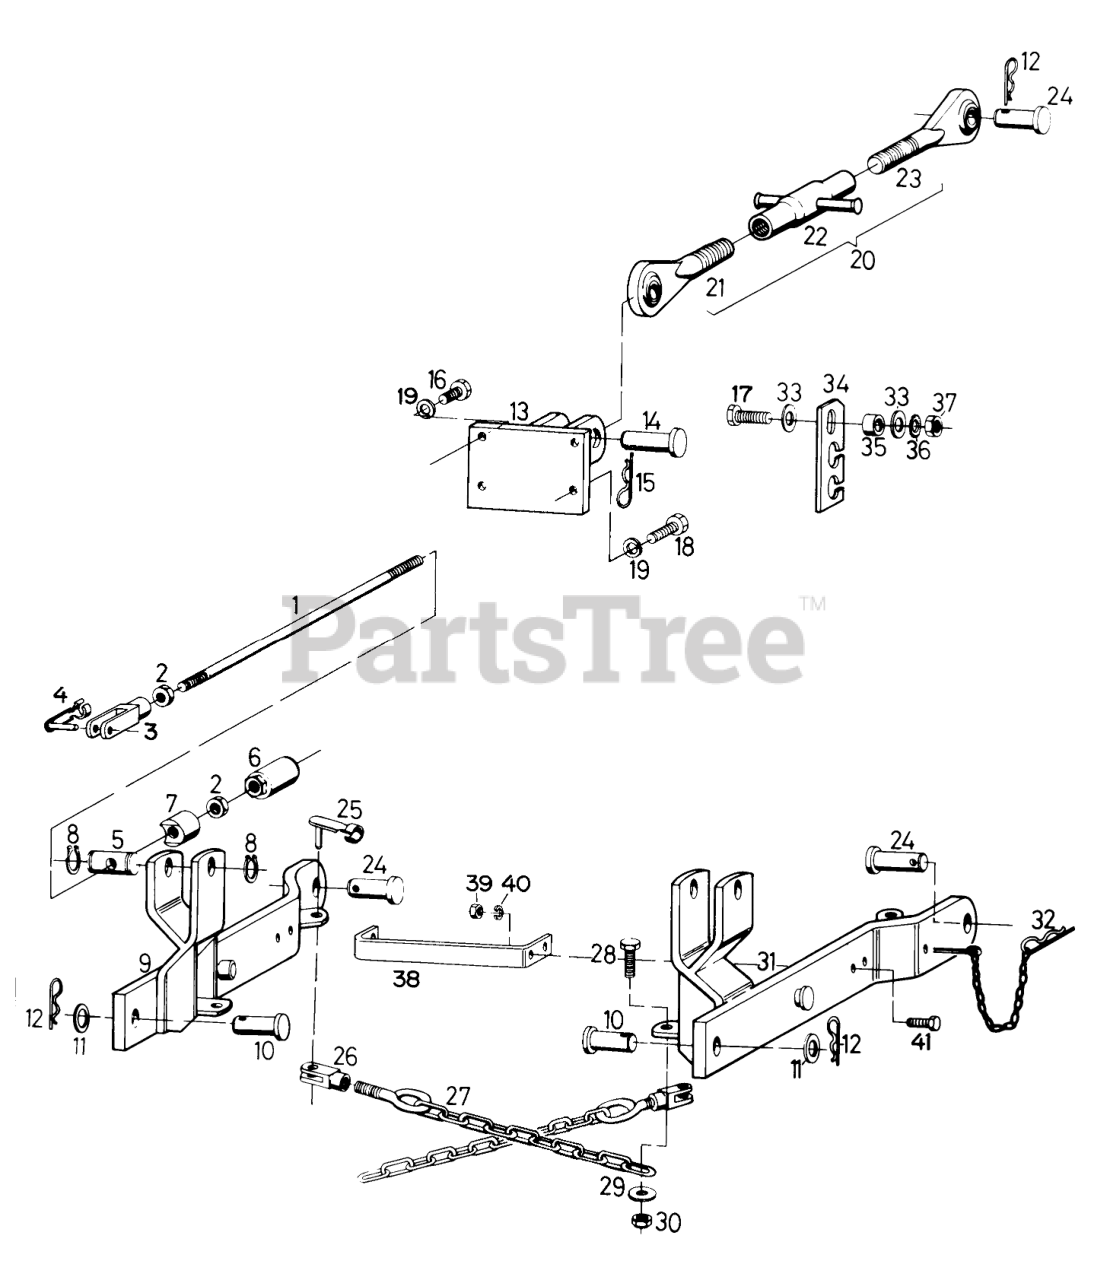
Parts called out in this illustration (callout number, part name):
1	Lift Rod
3	Clevis
4	Self Locking Clevis Pin
5	Trunnion
6	Adjuster
7	Collar
8	CIRCLIP
9	Lift Arm (Right)
10	Clevis Pin
11	Washer
12	Hairpin Cotter
13	Upper Link Support Bracket
14	Clevis Pin
15	Hairpin Cotter
19	Lockwasher
20	Upper Link Assy.
21	Link End R.H.
22	Turnbuckle
23	Link End L.H.
24	Clevis Pin
25	Self Locking Clevis Pin (Small)
26	Clevis (Small)
27	Sway Chain
29	Washer
31	Lift Arm (Left)
32	Hairpin Cotter & Chain
33	Washer
34	Latch Link
35	Spacer
36	Lockwasher
38	Stabilizer
40	Washer
